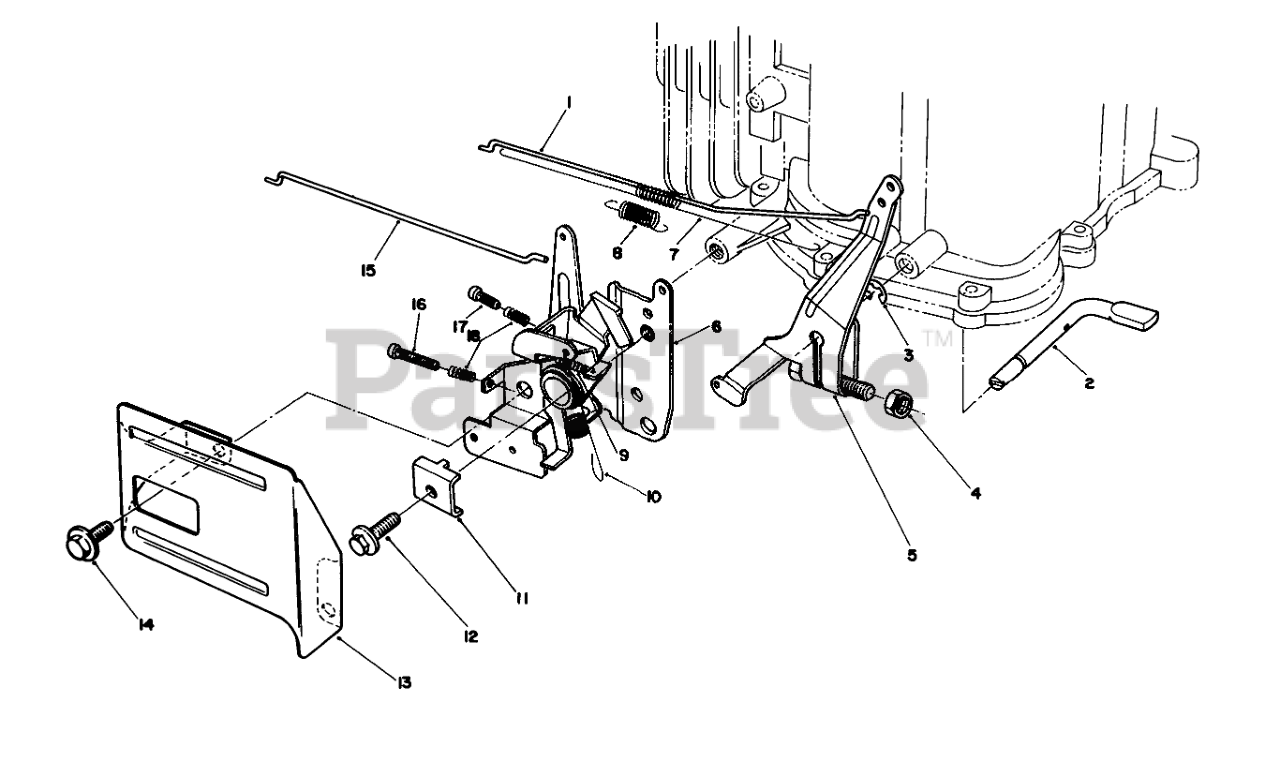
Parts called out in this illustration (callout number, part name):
1	Rod-Carburetor
2	SHAFT
3	E-RING
4	Nut
5	ARM ASM
6	THROTTLE
7	SPRING
8	SPRING
9	SPRING
10	SPRING
11	CLAMP-CABLE
13	THROTTLE GUARD
15	Rod-Choke
16	SCREW
17	SCREW
18	SPRING
